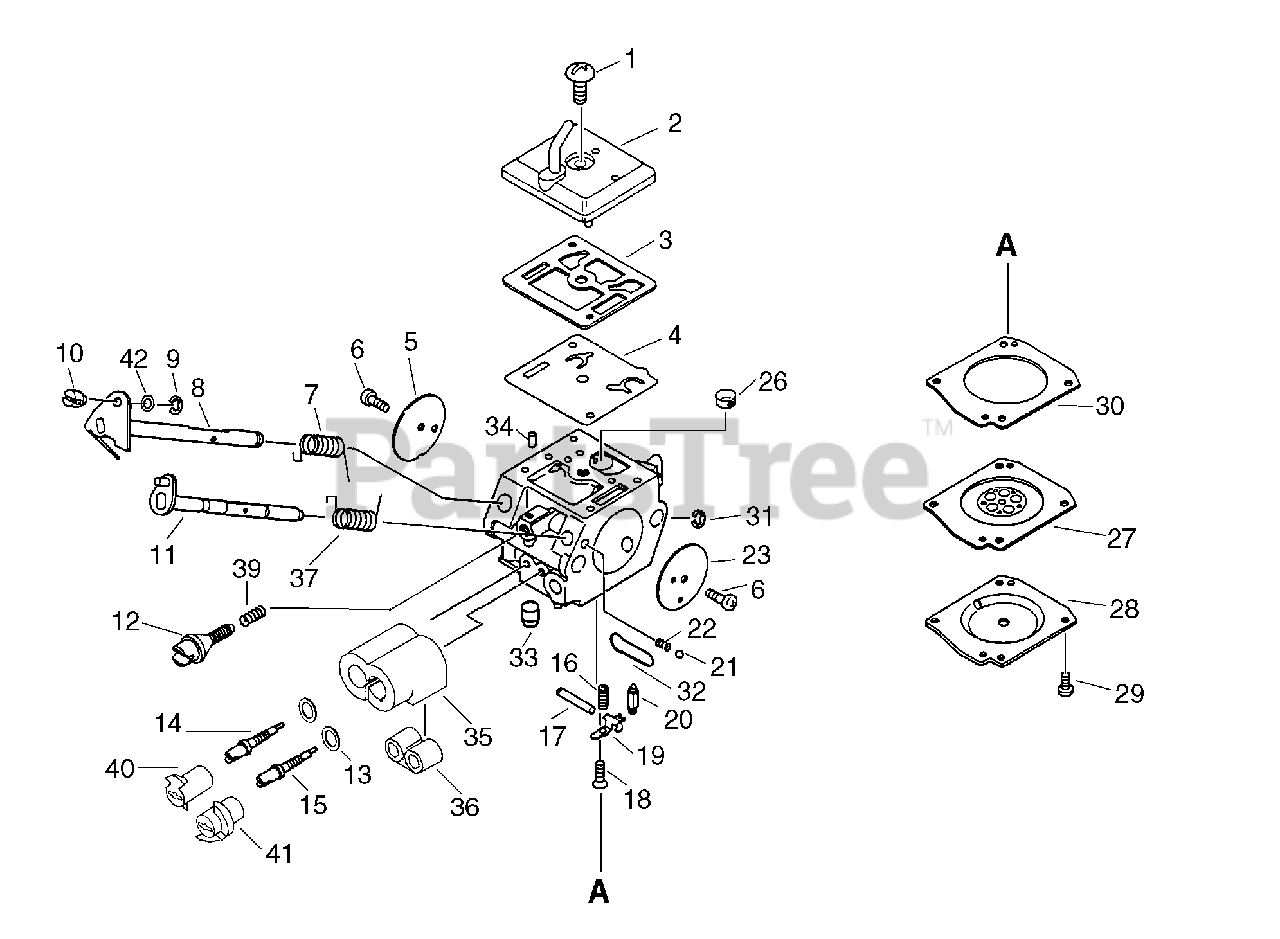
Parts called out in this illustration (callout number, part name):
1	SCREW, PUMP COVER
2	COVER, PUMP
3	GASKET, PUMP
4	DIAPHRAGM, PUMP
5	VALVE, THROTTLE
7	SPRING, RETURN
8	SHAFT, THROTTLE
9	RING, RETAINING
11	SHAFT, CHOKE
12	SCREW, THROTTLE ADJUST
14	NEEDLE - LOW SPEED
15	NEEDLE - HIGH SPEED
17	PIN, METERING LEVER
18	SCREW, METERING LEVER PIN
19	LEVER, METERING
20	VALVE, INLET NEEDLE
21	BALL, CHOKE
22	SPRING
23	VALVE, CHOKE
26	STRAINER
27	DIAPHRAGM
28	COVER, DIAPHRAGM
30	GASKET, METERING
31	RING, RETAINING
32	PLUG, WELCH
33	NOZZLE, CHECK VALVE
34	PIECE, FRICTION
35	RETAINER, LIMITER CAP
36	SCREW, BOOT ADJUST
37	SPRING, CHOKE RETURN
39	SPRING, IDLE ADJUST
40	CAP, LIMITER
41	CAP, LIMITER
